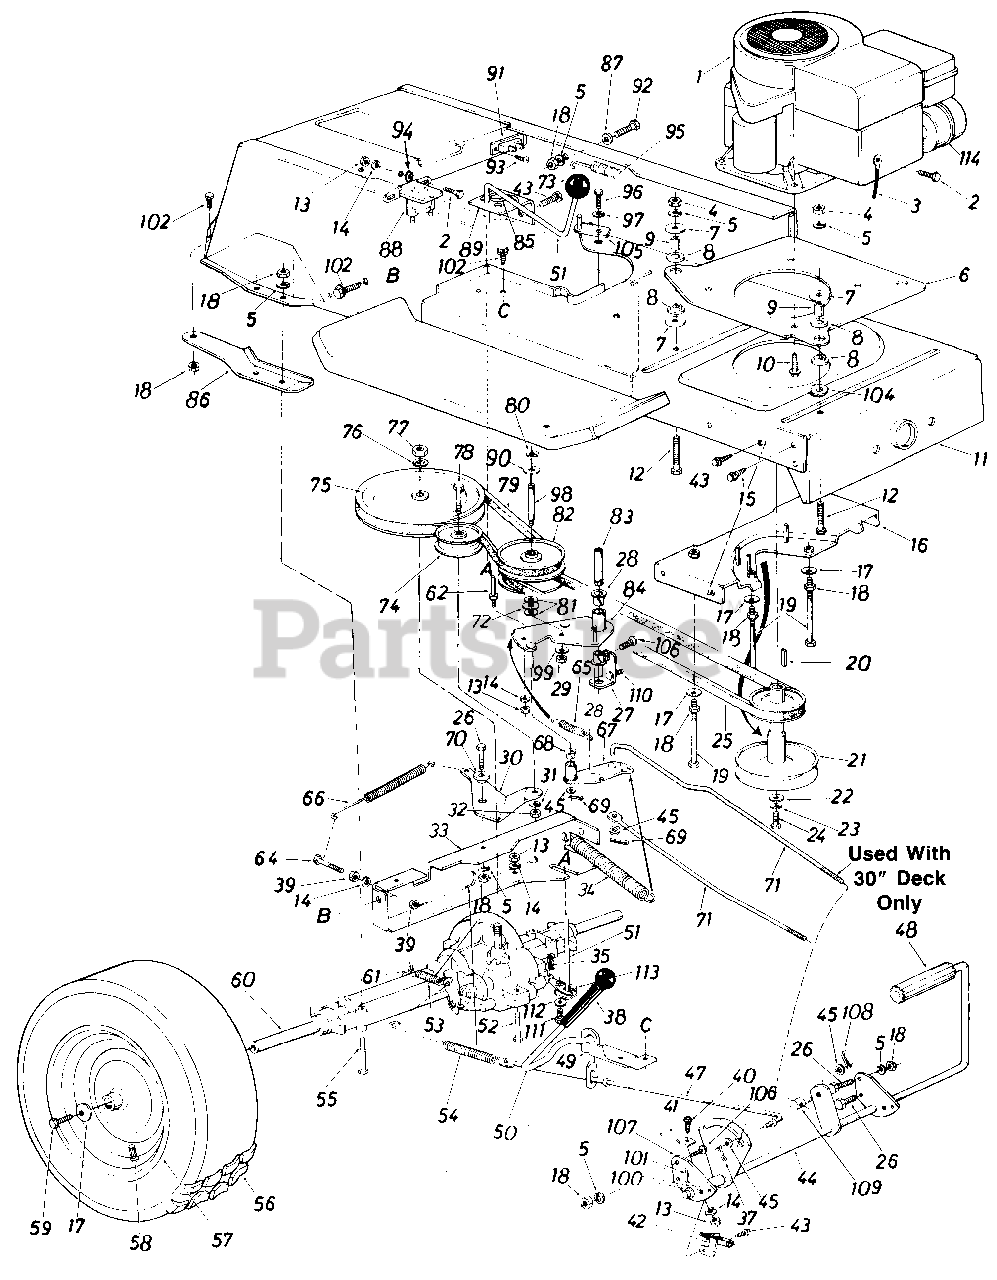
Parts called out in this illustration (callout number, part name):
1	Engine
2	Hex Bolt 1/4-20 x .62" Lg.*
3	Electric Graund Wire
4	Hex Nut 5/16-24 Thd.*
5	L-Wash. 5/16" I.D.*
6	Engine Mounting Plate
7	Fl-Wash. .320" I.D. x 1.25"
8	Engine Mounting Grommet
9	Spacer
10	Hex Bolt 3/8-16 x 1.25" Lg.
11	Lower Frame Ass'y.
12	Hex Bolt 5/16-24 x 1.25"*
13	Hex Nut 1/4-20 Thd.*
14	L-Wash. 1/4" I.D.*
15	Hex Wash. Hd. AB-Tap Scr. 5/16" x.75" Lg.
16	Belt Guard Brkt. Ass'y.
17	Bell-Wash. .345" I.D. x .88"
18	Hex Nut 5/16-18 Thd.*
19	Hex Bolt 5/16-18 x 5.25" Lg.
20	Sq. Key 1/4" x 1/4" x 2.00"
21	Engine Pulley-30" R.D.
22	Fl-Wash. 7/16" I.D. x 1.25"
23	L-Wash. 7/16" I.D.*
24	Hex Bolt 7/16-20 x 1.50" Lg.
25	Variable-Speed Belt
27	Bearing Shaft Bracket Ass'y.
28	Flanged Nyliner Brg. 5/8" I.D. x .88" Lg.
29	Hex Nut 3/8-24 Thd.*
30	Idler Bracket
31	L-Wash. 3/8" I.D.*
32	Hex Nut 3/8-24 Thd.*
33	Transaxle Support Brkt.
34	Ext. Spring .94" O.D. x 6.7
35	Inter. Cott-Pin
37	Cotter Pin 3/32" Dia. x .75"*
38	Grip-Black
39	Hex Nut 1/4-28 Thd.
40	Hex Bolt 1/4-20 x 1.00" Lg.*
41	Switch Actuator
42	Safety Switch
43	Hex Wash. Hd. S-Tap Scr. 1/4-20 x .50" Lg.
44	Clutch/Brake Pedal Ass'y.
45	Fl-Wash.
47	Brake Rod 20.9" Lg.
48	Foot Pad
49	Brake Lever Bracket
50	Hill Holder Brake Handle
51	Shift Lever Ass'y.
52	Hex Bolt 1/4-28 x 1.75" Lg.*
53	Ext. Spring .38" O.D. x 2.5"
54	Ext. Spring .59" O.D. x 7.08"
55	Hex Bolt 5/16-18 x 2.75"*
57	Wheel Rim Only
58	Air Valve
59	Hex Bolt 5/16-24 x .75" Lg.
60	Transaxle Complete
61	Brake Return Spring Anchor
62	Belt Guard Pin 1/4-20 Thd.
64	Hex Bolt 1/4-28 x 1.25" Lg.
65	Ext. Spring
66	Ext. Spring .62" O.D. x 6.12"
67	Variable Speed Torque Brkt. Ass'y.
68	Flanged Bearing
69	Cotter Pin 3/32" Dia.*
70	Shoulder Spacer .27" Lg.
71	Speed Control Link
72	Truss Bearing .56 Dia. x 1 .25"
73	Ball Knob
74	Fl-Idler Pulley 3.25" x 1.0"
75	1/2" "V"-Pulley 8.0" O.D. x .501 " I.D.
76	L-Wash. 1/2" I.D.
77	Hex Jam Nut 1/2-20 Thd.
78	Hex Bolt 3/8-24 x .75" Lg.
79	Variable Speed Belt
80	Snap Ring .56" Dia.
81	Fl-Wash.
82	Variable Speed Pulley Ass'y. 5" O.D.
83	Bearing Shaft
84	Variable Speed Brkt. Ass'y.
85	Comp. Spring-Clip
86	Transaxle Support Brkt.-R.H.
87	Fl-Wash. .34 I.D. x 1.12 O.D.
88	Solenoid
89	Shift Lever Bracket
90	Teflon Washer
91	Circuit Breaker
92	Hex Bolt 5/16-18 x 1.50" Lg.
93	Truss Hd. Phil. Scr. #10 x 1/2" Lg
94	Ext. L-Wash. 1/4" I.D.
95	Ext. Spring .99" O.D. x 11"
96	Hex Bolt 3/8-24 x .75" Lg.
97	Bell-Wash. .38" I.D. x .88"
98	Shaft .56" Dia. x 3.875" Lg.
99	Bell-Wash. .39" I.D. x 1.12"
100	Fl-Wash.
101	Cotter Pin 3/32" Dia. x 1.0
102	Hex Wash. Hd. Scr. 5/16-18 x.62" Lg.
104	Fl-Wash. .32" I.D. x 1.25"
105	Belt Guard
106	Truss Mach. Scr. 5/16-18 x .75" Lg.
107	Pedal Bracket
108	Cotter Pin 3/32" Dia. x .75"
109	Ferrule
110	Truss Phillips Hd. Scr. 5/16-18 x 1.0" Lg.
111	Hex Bolt 1/4-28 x .50" Lg.
112	Bell-Wash. .265" I.D. x .75"
113	Shift Lever Link Ass'y.
114	Muffler
